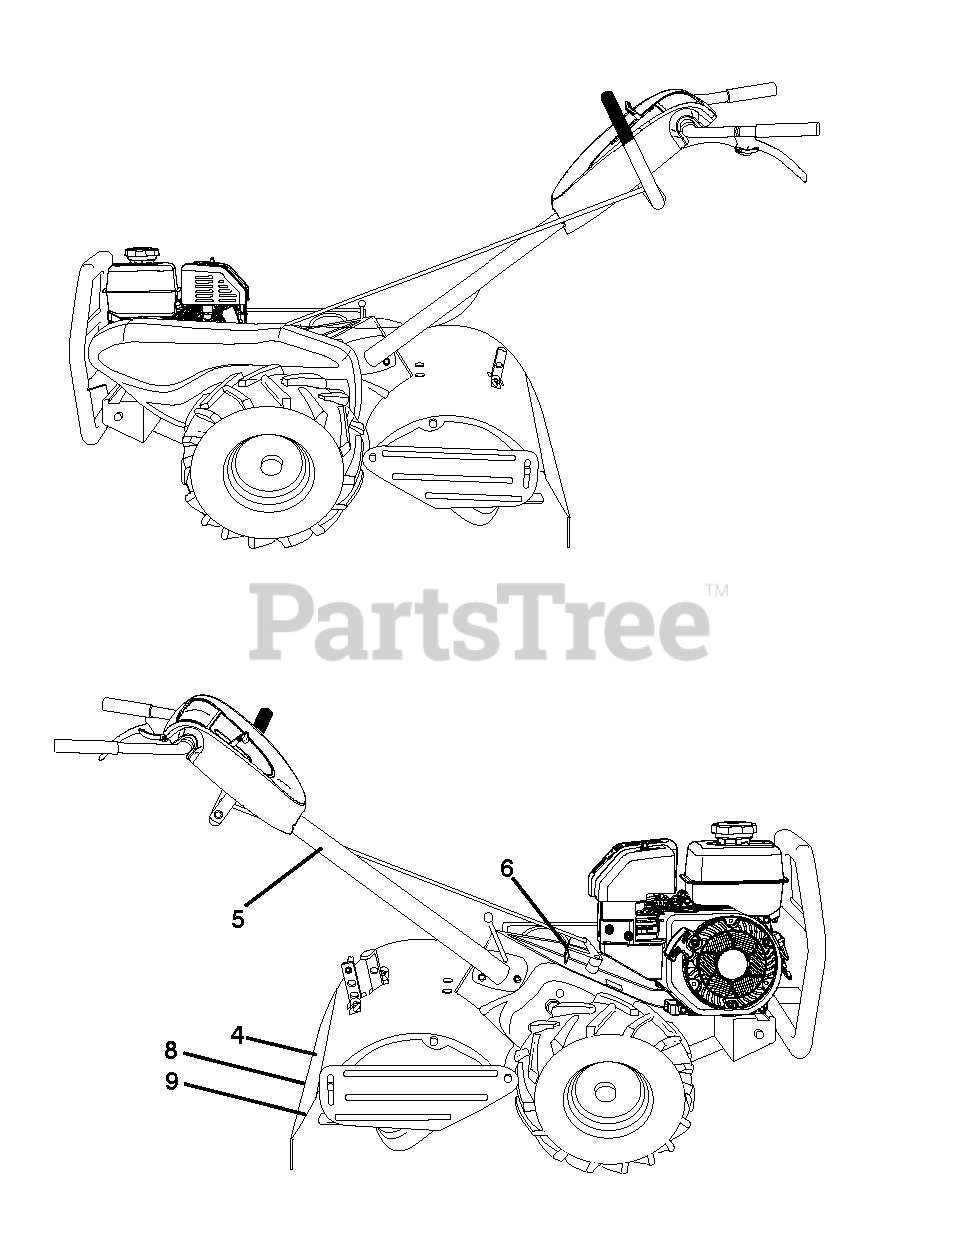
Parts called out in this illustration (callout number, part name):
4	DECAL TILLER TINE SHIELD GRAPH
5	DECAL.PLACEMENT.HAND.SYMBOLS
6	DECAL.INDICATOR.SHIFT.DRT.SYM
8	DECAL TILLER TINE SHIELD GRAPH
9	DECAL.WARNING.4-SYM.TILLER.INT
